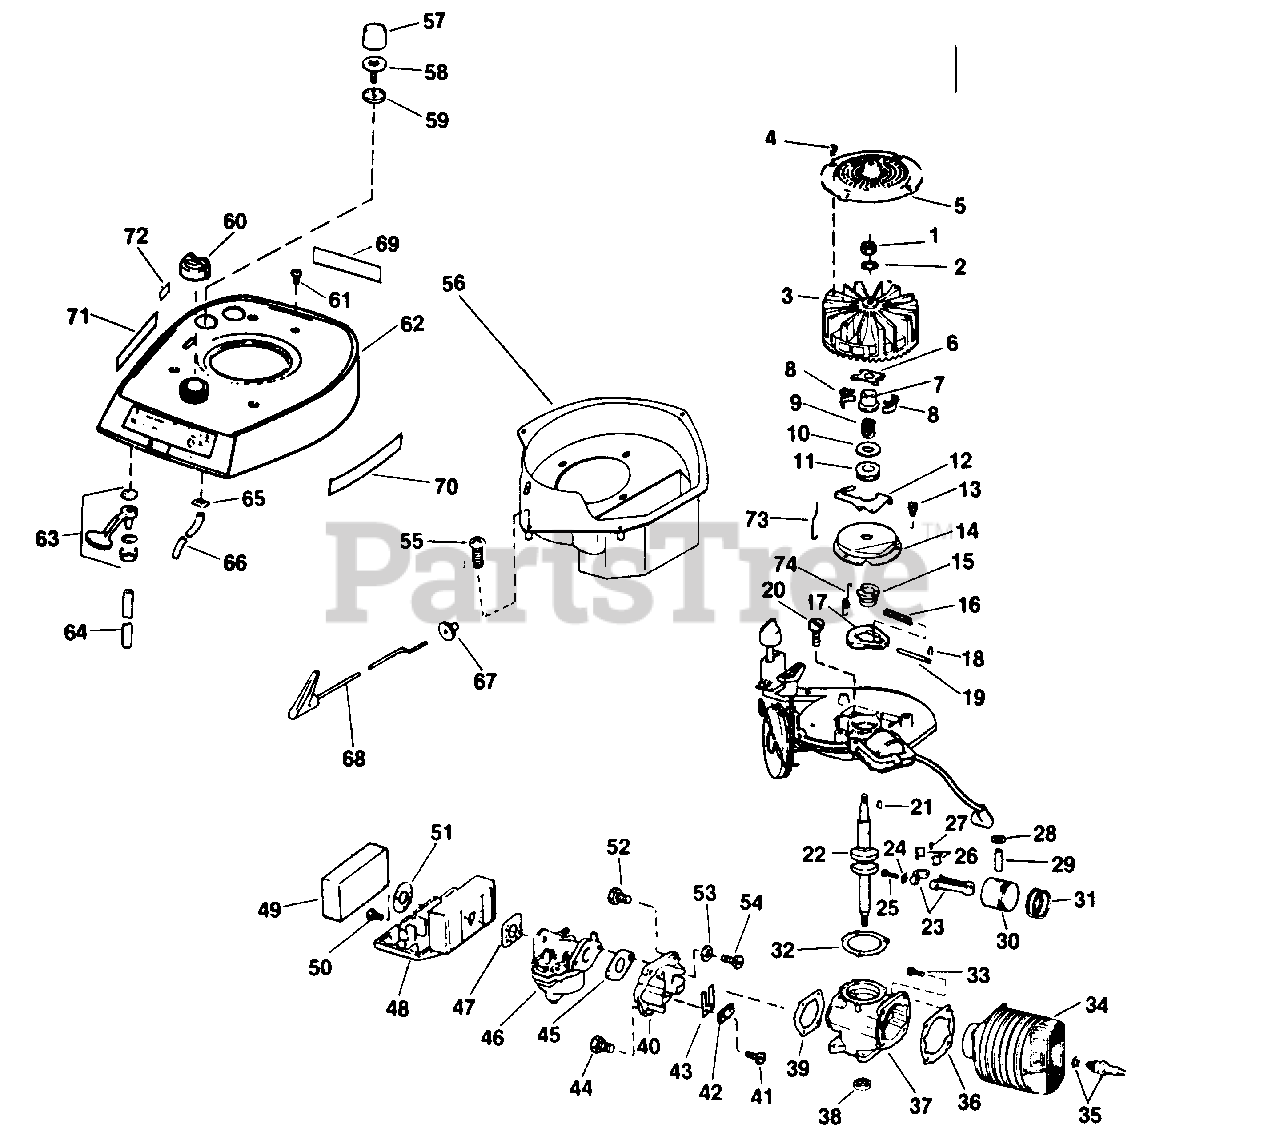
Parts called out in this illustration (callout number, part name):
1	Nut-Flywheel
2	Lockwasher-Flywheel
3	Flywheel & Screen Assy.
4	Screw-Thd. Cutting
5	Screen & Cup
6	Yoke-Governor
7	Collar-Governor
8	Weight-Governor
9	Spring-Governor
10	Thrust Washer
11	Collar-Thrust
12	Lever-Governor
13	Screw-Attach. Dust Cover
14	Dust Cover
15	Cam-Spark Advance
16	Spring-Spark Advance
17	Flyweight-Spark Advance
18	Retainer-Spring
19	Pin-Spark Advance
20	Scr.-Arm Pl. to Crankcase
21	Key-Crankshaft
22	Crankshaft
23	Connect. Rod Assy.
24	Lockpl.-Connect. Rod Scr.
25	Screw-Connect. Rod
26	Liners-Connect. Rod
27	Needle Brg. Set
28	Retaining Ring
29	Wrist Pin
30	Piston
31	Ring Set
32	Gasket-Crkc. to Arm Pl. .005 in.
32	Gasket-Crkc. to Arm. Pl. .010 in.
33	Screw-Cyl. to Crankcase
34	Cylinder and Sleeve Assembly
35	Spark Plug and Gasket
36	Gasket-Cyl. to Crankease
37	Crankcase and Seal Assy.
38	Oil Seal
39	Gasket-Reed Plate
40	Reed Plate Assembly
41	Screw-Machine
42	Plate-Back-up
43	Reed
44	Screw-H.H. Reed Pl. to Crkc.
45	Gasket-Carburetor
46	Carburetor Assy.
47	Gasket
48	Case-Air Filter
49	Element
50	Screw
51	Washer
52	Screw
53	Washer
54	Screw
55	Screw-Air Baffle
56	Air Baffle
57	Bulb-Primer
58	Base-Primer
59	Cap-Primer
60	Cap-Gas Tank
61	Screw-Cover Mtg.
62	Cover-Engine
63	Shut-off Valve
64	Fuel Hose
65	Fastener
66	Gas Line
67	Grommet
68	Knob & Rod
69	Decal-Lawn-Boy
70	Decal-RH
71	Decal-LH
72	Decal-Primer
73	Rod Governor
74	Spring-Variable Speed
